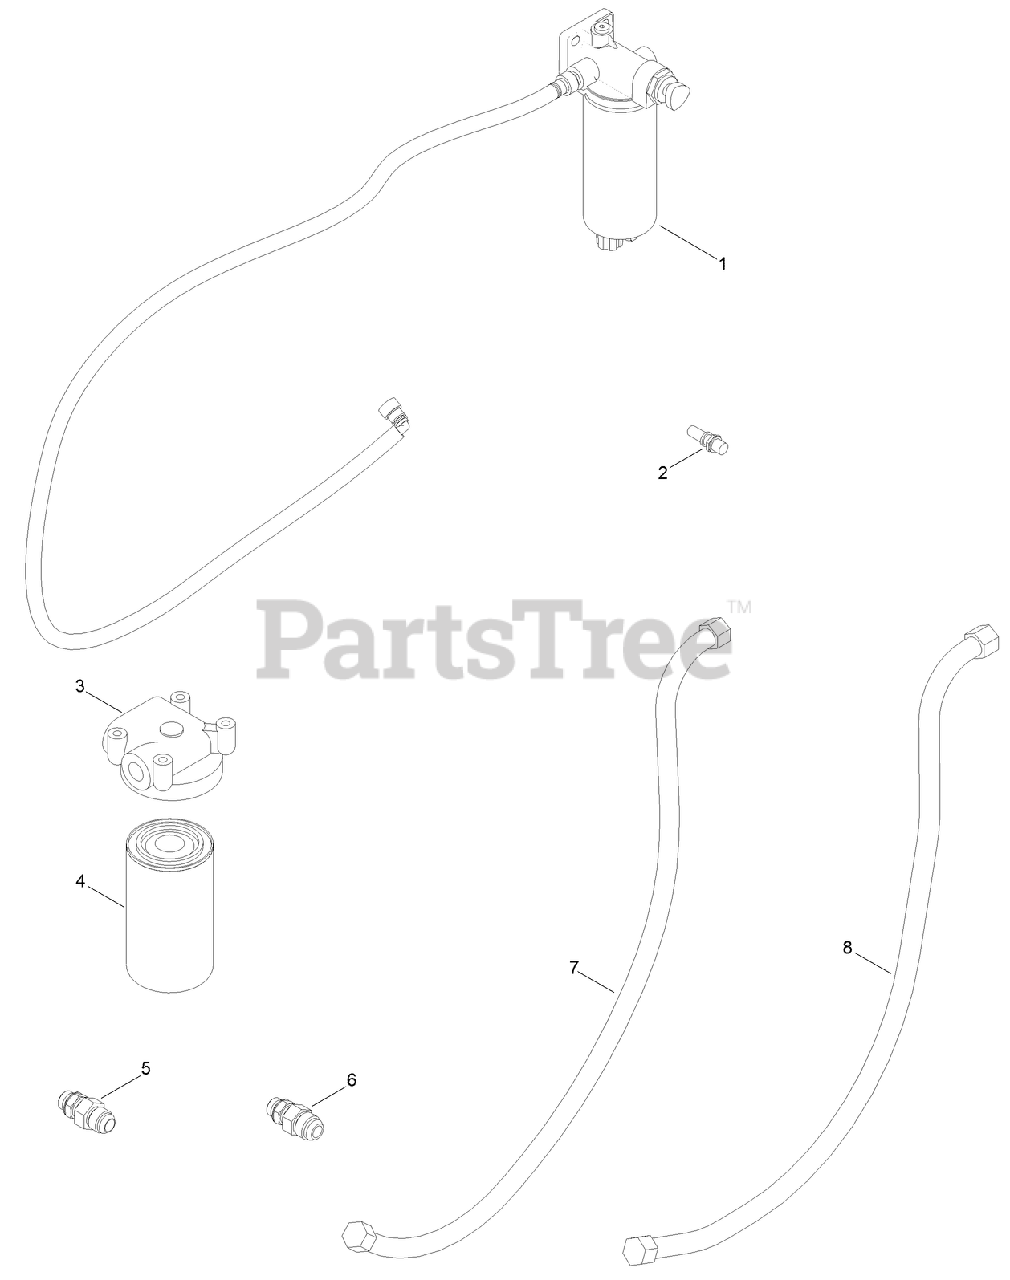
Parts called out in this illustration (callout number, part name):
1	FUEL FILTER ASM
2	FITTING-FUEL
3	HEAD-FILTER, OIL
4	FILTER-OIL
5	FITTING-OIL
6	FITTING-OIL
7	HOSE-OIL
8	HOSE-OIL
